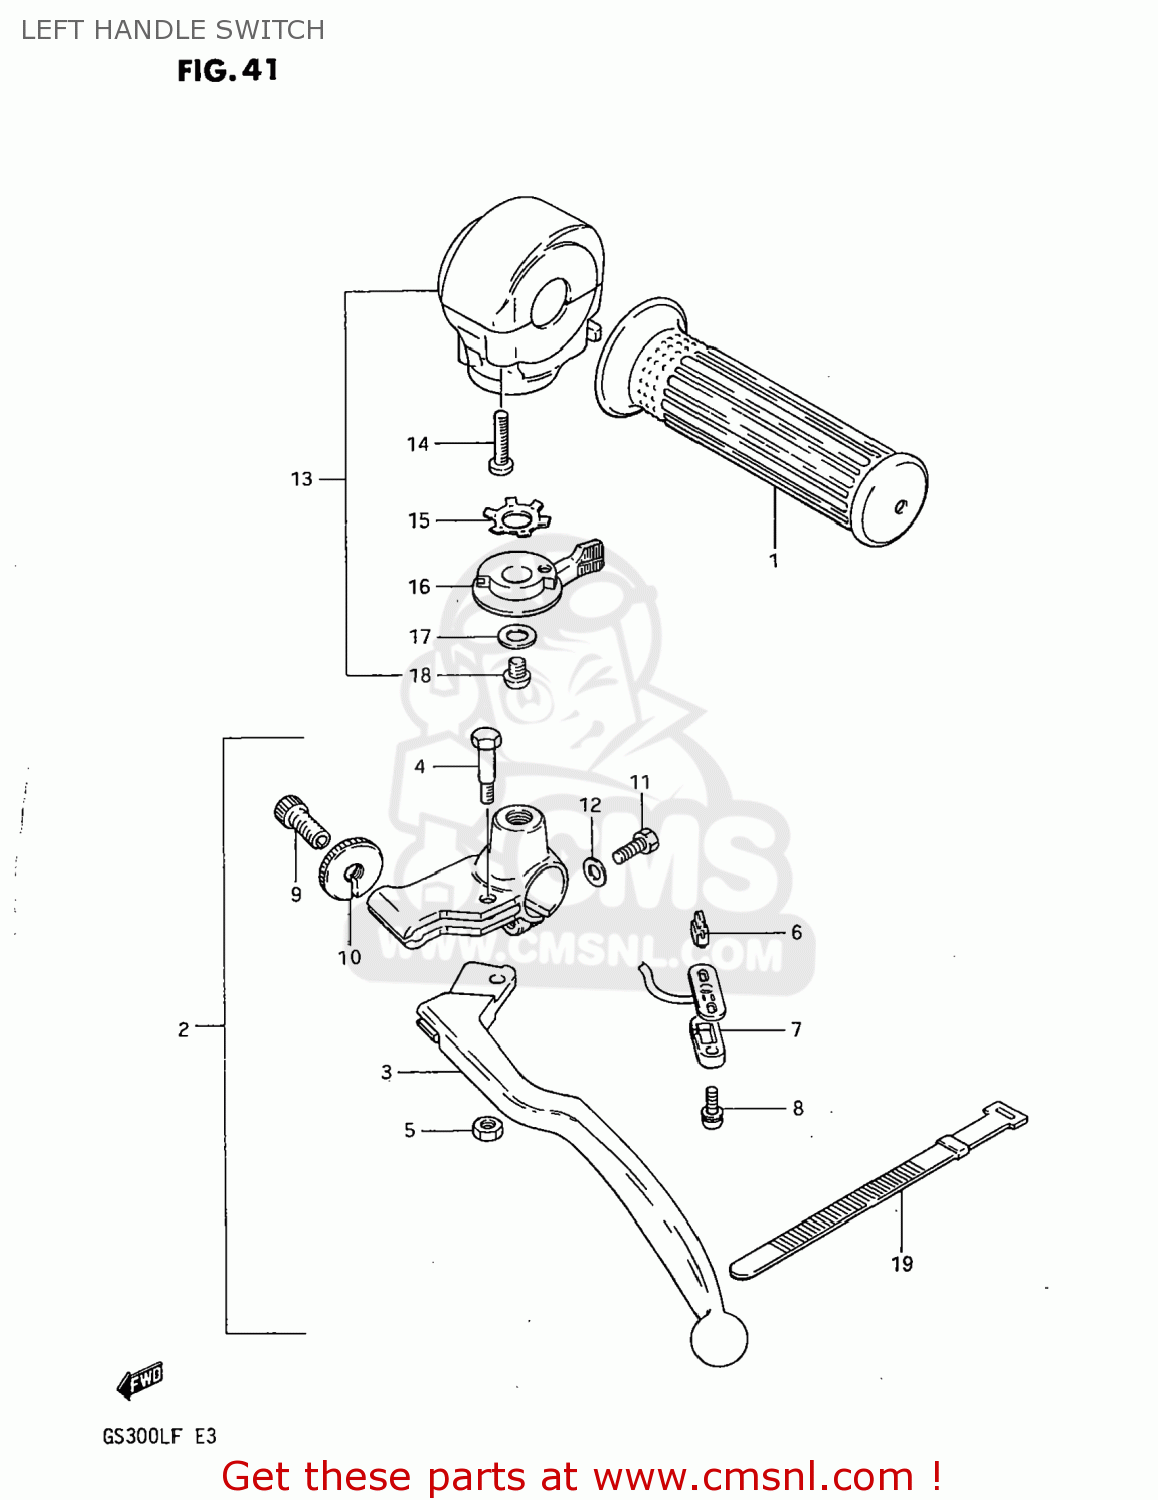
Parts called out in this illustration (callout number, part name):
1	GRIP,LEFT
2	LEVER ASSEMBLY
3	LEVER,CLUTCH
4	BOLT,LEVER PIVOT
5	NUT
6	CONTACT,SWITCH
7	COVER,FR BK TERMINAL BASE
8	SCREW
9	ADJUSTER,CABLE
10	NUT,CABLE ADJUSTER
11	BOLT
12	WASHER
13	SWITCH ASSEMBLY,HANDLE,LEFT
14	SCREW
15	WASHER
16	LEVER,STARTER
17	WASHER 6MM
18	SCREW
19	CLAMP(L:120)
